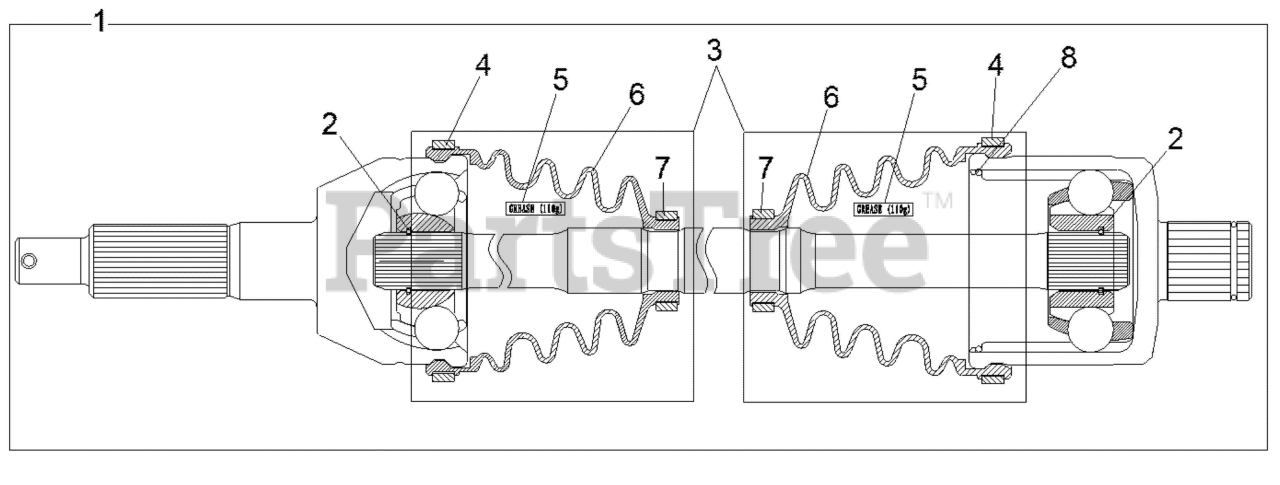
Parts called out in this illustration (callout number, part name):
1	ASM-DRIVESHAFT,REAR
2	CIRCLIP
3	KIT-BOOT(PR-8071)
4	CLAMP-LARGE(PR-0027)
5	GREASE(K575/VW738)
6	BOOT(PR-0025)
7	CLAMP-SMALL(PR-0026)
8	RING, RUBBER
